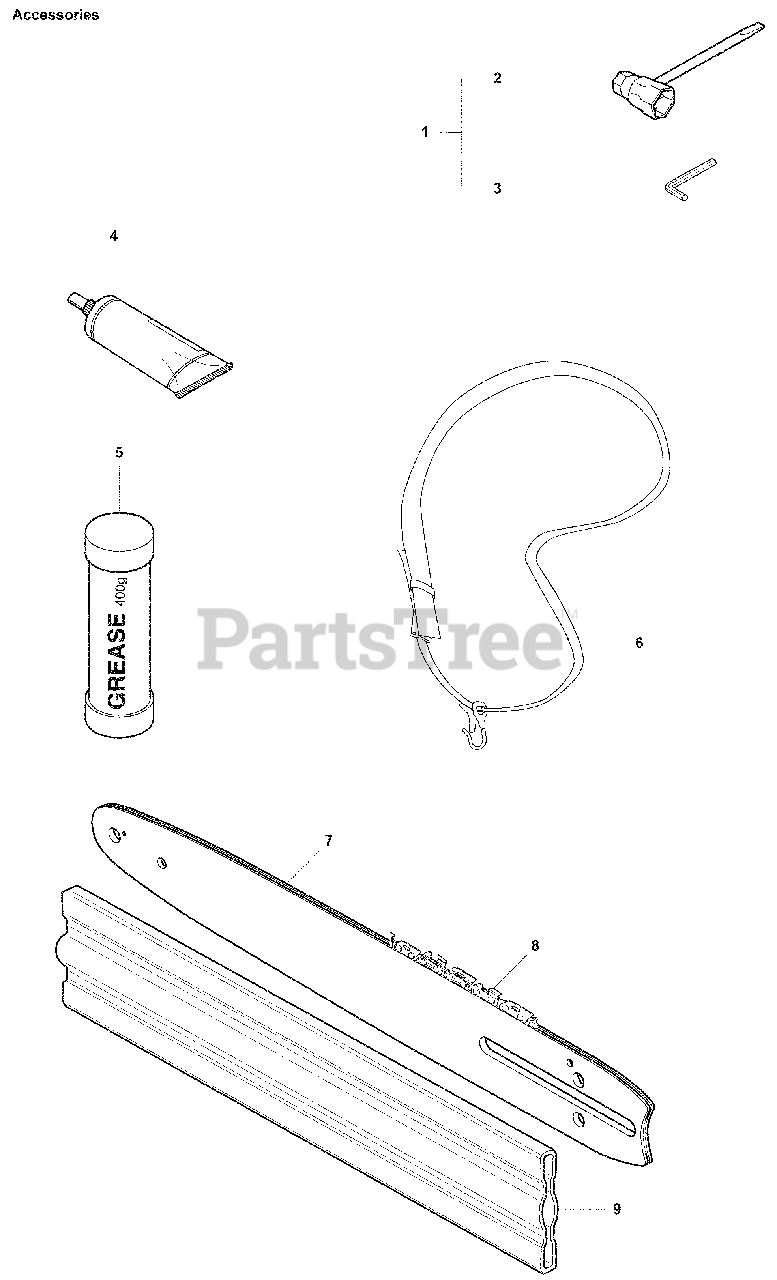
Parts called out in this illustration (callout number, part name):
1	ACCESSORY KIT
2	Combi Tool
3	Allen Wrench, 4mm
4	Gear Grease, Tube
5	GREASE 400 GRAMS
6	Shoulder Strap with Sign
7	Guide Bar, 10" HL280-40 3/8" .050
7	Guide Bar, 12" Hl280-45 3/8 .050
8	H36-40 CHAIN LOOP
8	Saw Chain, 12" H3745 38.050
